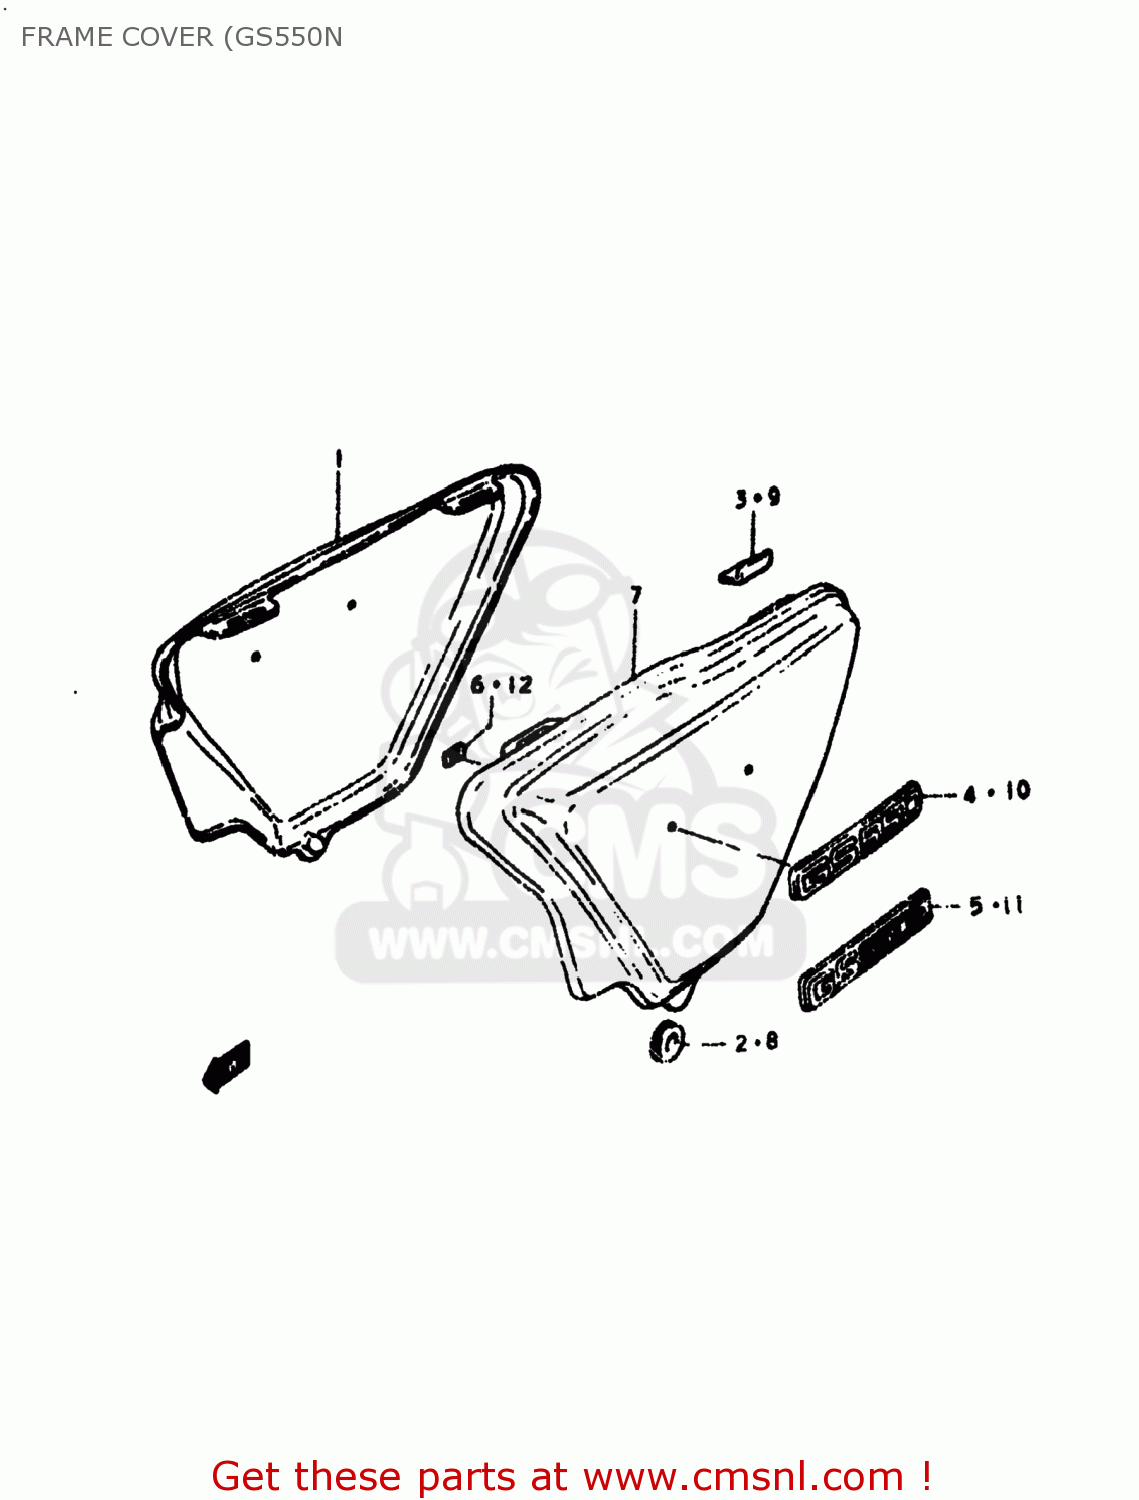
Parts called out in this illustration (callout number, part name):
1	COVER,FRAME,RIGHT
2	CUSHION
3	CUSHION,FRAME COVER
4	EMBLEM,FRAME COVER
5	EMBLEM,FRAME COVER
6	NUT
7	COVER,FRAME,LEFT
8	CUSHION
9	CUSHION,FRAME COVER
10	EMBLEM,FRAME COVER
11	EMBLEM,FRAME COVER
12	NUT
